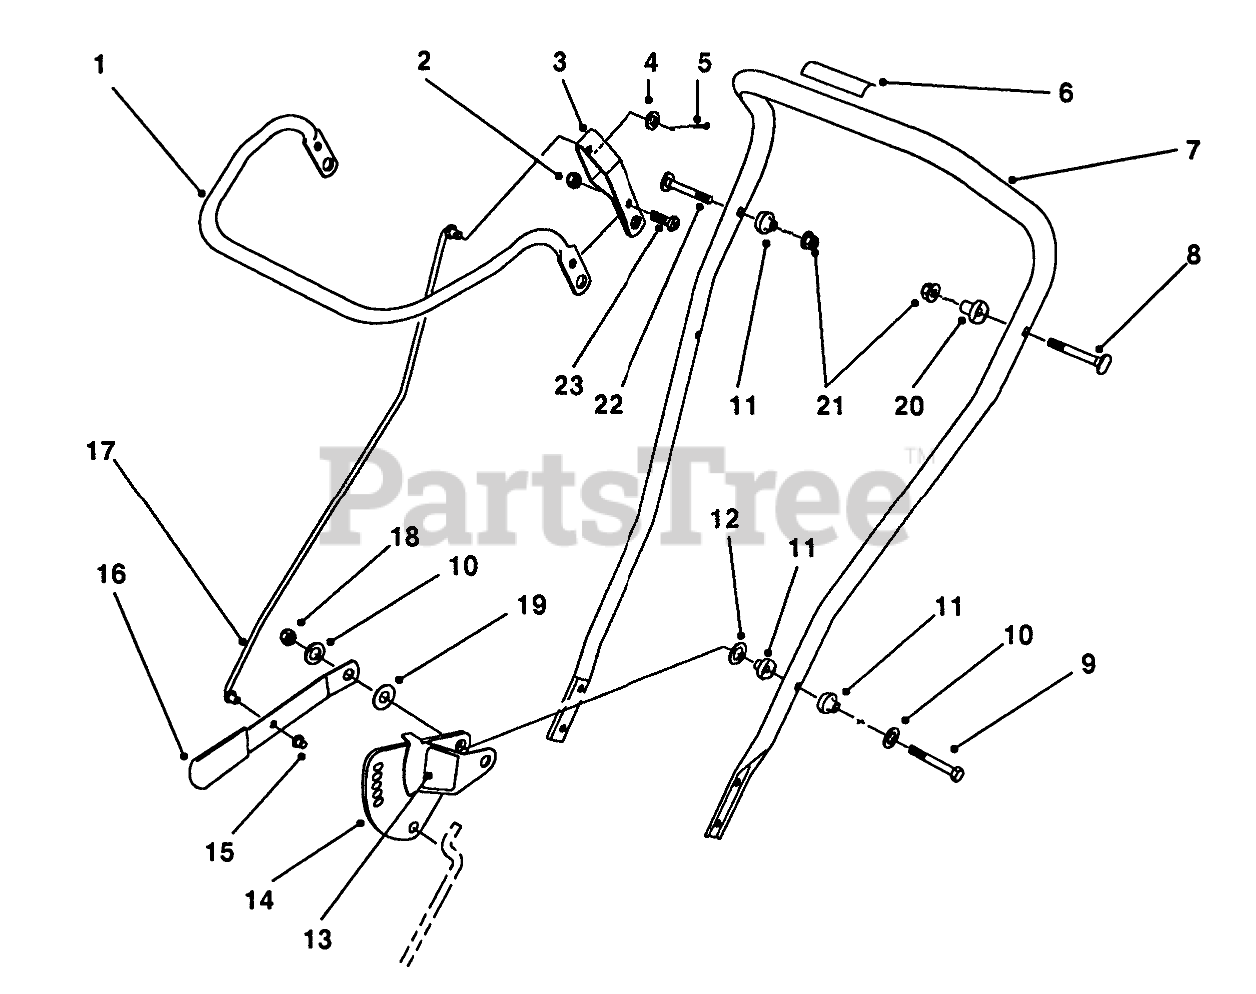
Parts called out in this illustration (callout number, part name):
1	Bar-Control
2	NUT-LOCK, NI
3	CONTROL BAR BRKT.
4	WASHER-FLAT
5	PIN-COTTER
6	DECAL
7	UPPER HANDLE
8	5/16-18 X 2 HNDLE SCREW
9	SCREW-HH
10	WASHER-PLAIN
11	PIVOT SPACER
12	WASHER
13	DECAL
14	ADJ.PLATE WA
15	PUSHNUT
16	ADJ.HANDLE
17	UPPER CONTROL ROD
18	NUT-LOCK, NI
19	WASHER
20	SPACER-SUPPORT
21	NUT-LOCK, NI
22	SCREW-HANDLE
23	SCREW-HSBH
